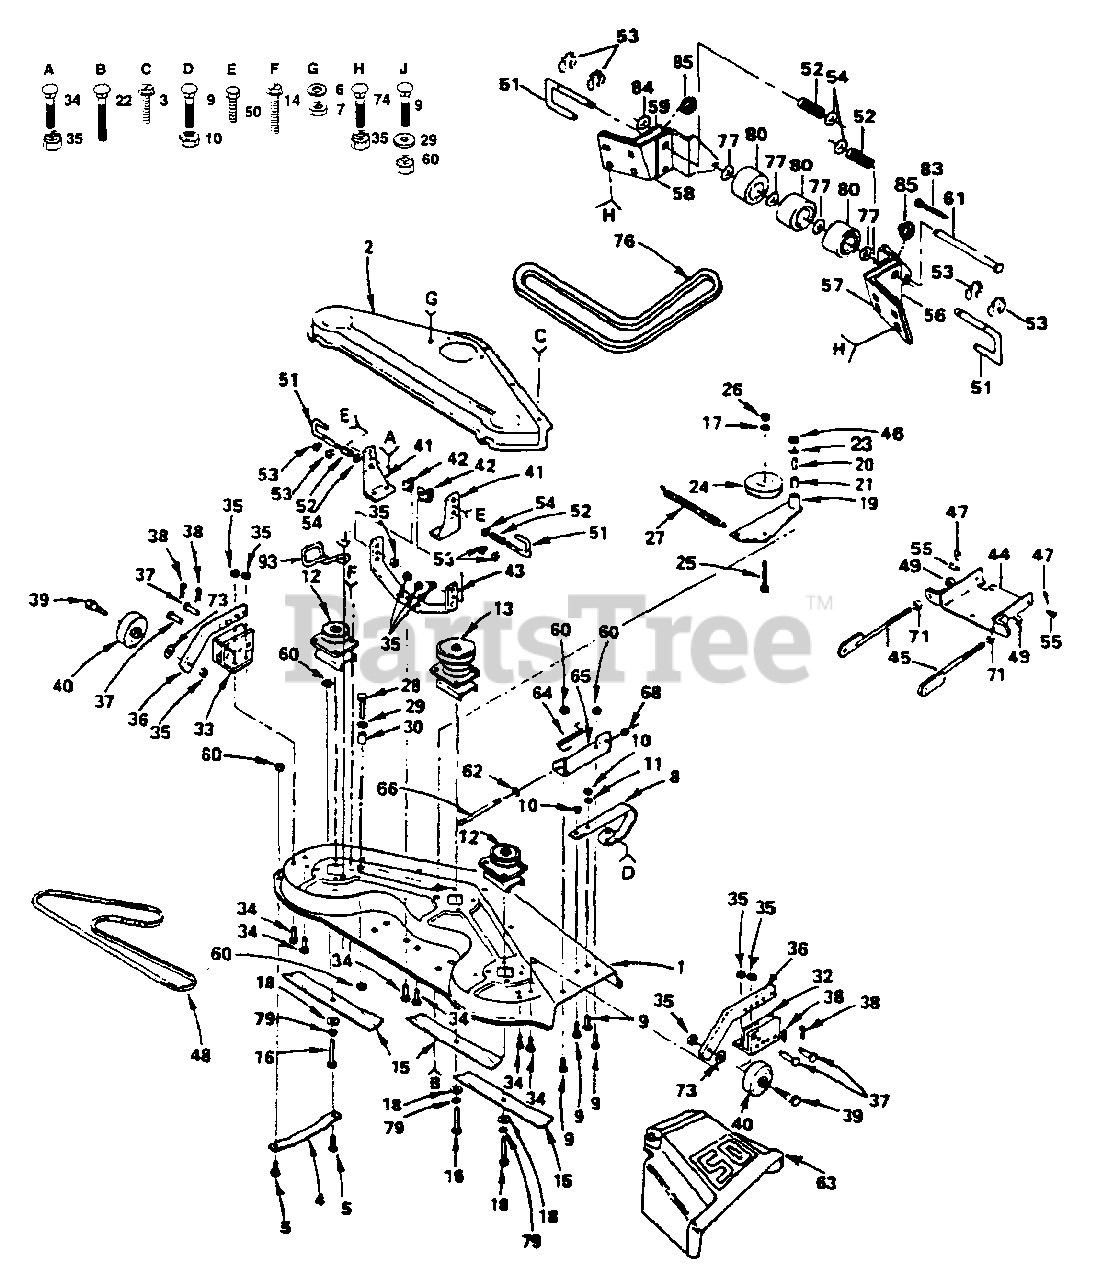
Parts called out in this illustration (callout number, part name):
1	Housing, Mower (AYP part number)
2	Cover, Drive, Deck (AYP part number)
3	Screw, Hex Washer Thd. Roll 5/16-18 x 1/2 (AYP part number)
4	Runner, L.H. (AYP part number)
5	Bolt, Carriage 5/16-18 x 5/8 (AYP part number)
6	Washer, Lock 5/16 (AYP part number)
7	Nut, Hex 5/16-18 (AYP part number)
8	Runner, R.H. (AYP part number)
9	Bolt, Carriage 5/16-18 x 3/4
10	Locknut 5/16-18 (AYP part number)
11	Washer 11/32 x 11/16 x 16 Gauge (AYP part number)
12	Mandrel, Secondary (AYP part number)
13	Mandrel, Primary (AYP part number)
14	Screw, Hex Washer Thd. Roll 3/8-16 x 3/4 (AYP part number)
16	Bolt, Hex 3/8-24 x 1-1/2 Grade 5 (AYP part number)
17	Washer, Lock 3/8 (AYP part number)
18	Washer 13/32 x 1-1/4 x 12 Gauge (AYP part number)
19	Arm Assembly, Idler (AYP part number)
20	Liner, Bearing (AYP part number)
21	Bearing (AYP part number)
22	Bolt, Carriage 5/16-18 x 1-1/4 Gr. 5 (AYP part number)
23	Washer 11/32 x 1-1/8 x 16 Gauge (AYP part number)
24	Pulley, Idler (AYP part number)
25	Bolt, Hex 3/8-16 x 1-1/2 (AYP part number)
26	Nut, Hex 3/8-16 (AYP part number)
27	Spring (AYP part number)
28	Bolt, Hex 5/16-18 x 1-1/4 Grade 5 (AYP part number)
29	Washer 11/32 x 3/4 x 16 Gauge (AYP part number)
30	Spacer Split (AYP part number)
32	Bracket, Ga. Wheel, R.H. (AYP part number)
33	Bracket, Ga. Wheel, L.H. (AYP part number)
34	Bolt, Carriage 3/8-16 x 3/4 (AYP part number)
35	Nut, Crownlock 3/8-16
36	Bar, Ga. Wheel (AYP part number)
37	Pin, Clevis (AYP part number)
38	Retainer, Spring (AYP part number)
39	Bolt, Shoulder (AYP part number)
40	Wheel, Gauge (AYP part number)
41	Bracket, Suspension (AYP part number)
42	Spacer (AYP part number)
43	Brace, Suspension (AYP part number)
44	Plate Assembly, Mower Suspension (AYP part number)
45	Bracket, Suspension (AYP part number)
46	Nut, Hex 5/16-18 (AYP part number)
47	Retainer, Spring (AYP part number)
48	V-Belt (AYP part number)
49	Nut, Crownlock 1/2-13 (AYP part number)
50	Bolt, Hex 3/8-16 x 1-3/8 (AYP part number)
51	Pin, Release (AYP part number)
52	Spring (AYP part number)
53	Ring, Klip (AYP part number)
54	Washer 17/32 x 5/8 x 16 Gauge (AYP part number)
55	Pin, Clevis (AYP part number)
56	Bracket, Outer, R.H. (AYP part number)
57	Bracket, Inner, R.H. (AYP part number)
58	Bracket, Inner, L.H. (AYP part number)
59	Bracket, Outer, L.H. (AYP part number)
60	Nut, Crownlock 5/16-18
61	Pin, Pivot (AYP part number)
62	Washer 11/32 x 5/8 x 16 Gauge (AYP part number)
63	Shield, Deflector (AYP part number)
64	Spring, Deflector (AYP part number)
65	Bracket, Deflector (AYP part number)
66	Rod, Hinge (AYP part number)
68	Nut, Push (AYP part number)
71	Nut, Hex 1/2-13 (AYP part number)
73	Washer 17/32 x 15/16 x 12 Gauge (AYP part number)
74	Bolt, Carriage 3/8-16 x 1 (AYP part number)
76	V-Belt (AYP part number)
77	Washer 15/32 x 1 x 10 Gauge (AYP part number)
79	Washer, Lock 3/8 (AYP part number)
80	Roller, Nose (AYP part number)
83	Pin Cotter (AYP part number)
84	Washer 15/30 x 1 x 16 Gauge (AYP part number)
85	Spacer (AYP part number)
93	Keeper, L.H. (AYP part number)
